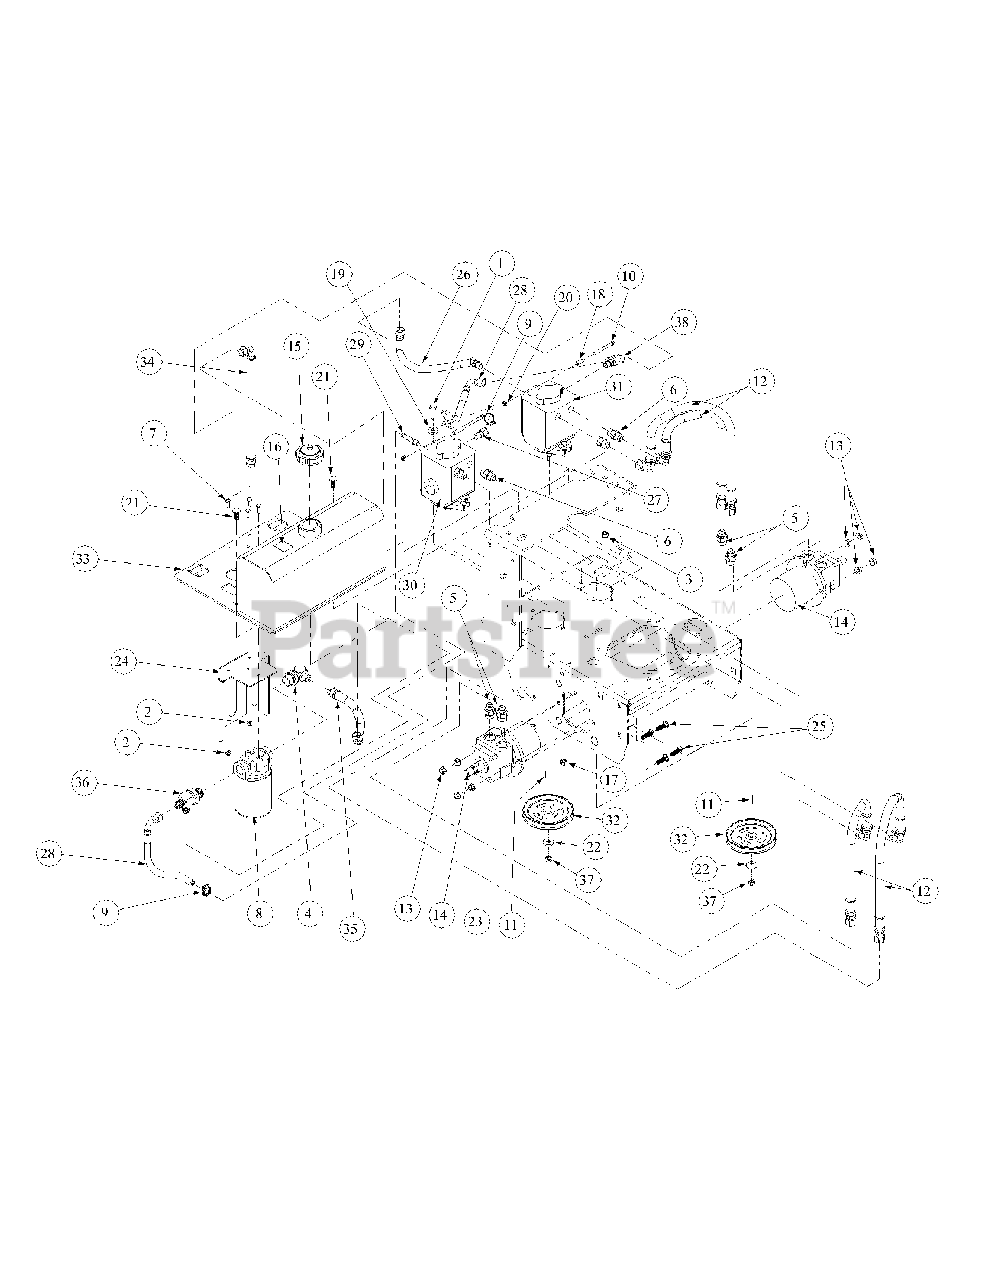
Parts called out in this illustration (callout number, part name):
1	Cap Screw, Standard, 3/8-16 x 1-1/4
2	Lock Nut Nylon Insert, 1/4-20
3	Lock Nut, 3/8-16
4	Elbow 90° 1/2 x 3/4
5	Fitting, Aeroquip
6	Fitting, Aeroquip
7	Cap Screw, 1/4-20 x 3/4
8	Filter Head 3/4
9	Worm Gear Clamp, 5/16-7/8
10	Cap Screw, Socket Head, 1/4-20 x 1-1/2 Zinc
11	Key, 3/16" x 7/8"
12	Reverse Pressure Hydraulic Hose Assembly
13	Flange Lock Hex Nut, 3/8-16
14	Hydraulic Motor, Wheel
15	Cap, Hydraulic Oil Tank
16	Oil Label, 20W-50
17	Lock Nut, 3/8-16
18	Spacer, Pump Release
19	Washer, Idler
20	Hex Lock Nut, 1/4-20
21	Carriage Bolt, 3/8-16 x 1.0
22	Bell Washer, .396 x 1.140 x .095
23	Woodruff Key, 3/16 x 3/4
24	Filter Guard Weldment
25	Carriage Bolt, 3/8-16 x 1.25
26	Left Pump Inlet Hose
27	Push On Fitting 45
28	Right Pump Inlet Hose
29	Push On Straight Fitting
30	Right Hand, Hydro Pump, BDP 10A 308
31	Left Hand, Hydro Pump, BDP 10A 413
32	Hydro Pump Pulley, 5.00 Dia
33	Fuel Tank Mounting Bracket and Integrated Hydraulic Tank
34	Left Hand, 14.25 Return Hose Assembly
35	9.5" Supply Hose Assembly
36	Tee Fitting, 3/4 x 1/2 x 1/2
37	Hex Nut, 3/8-24
38	Tee Fitting
